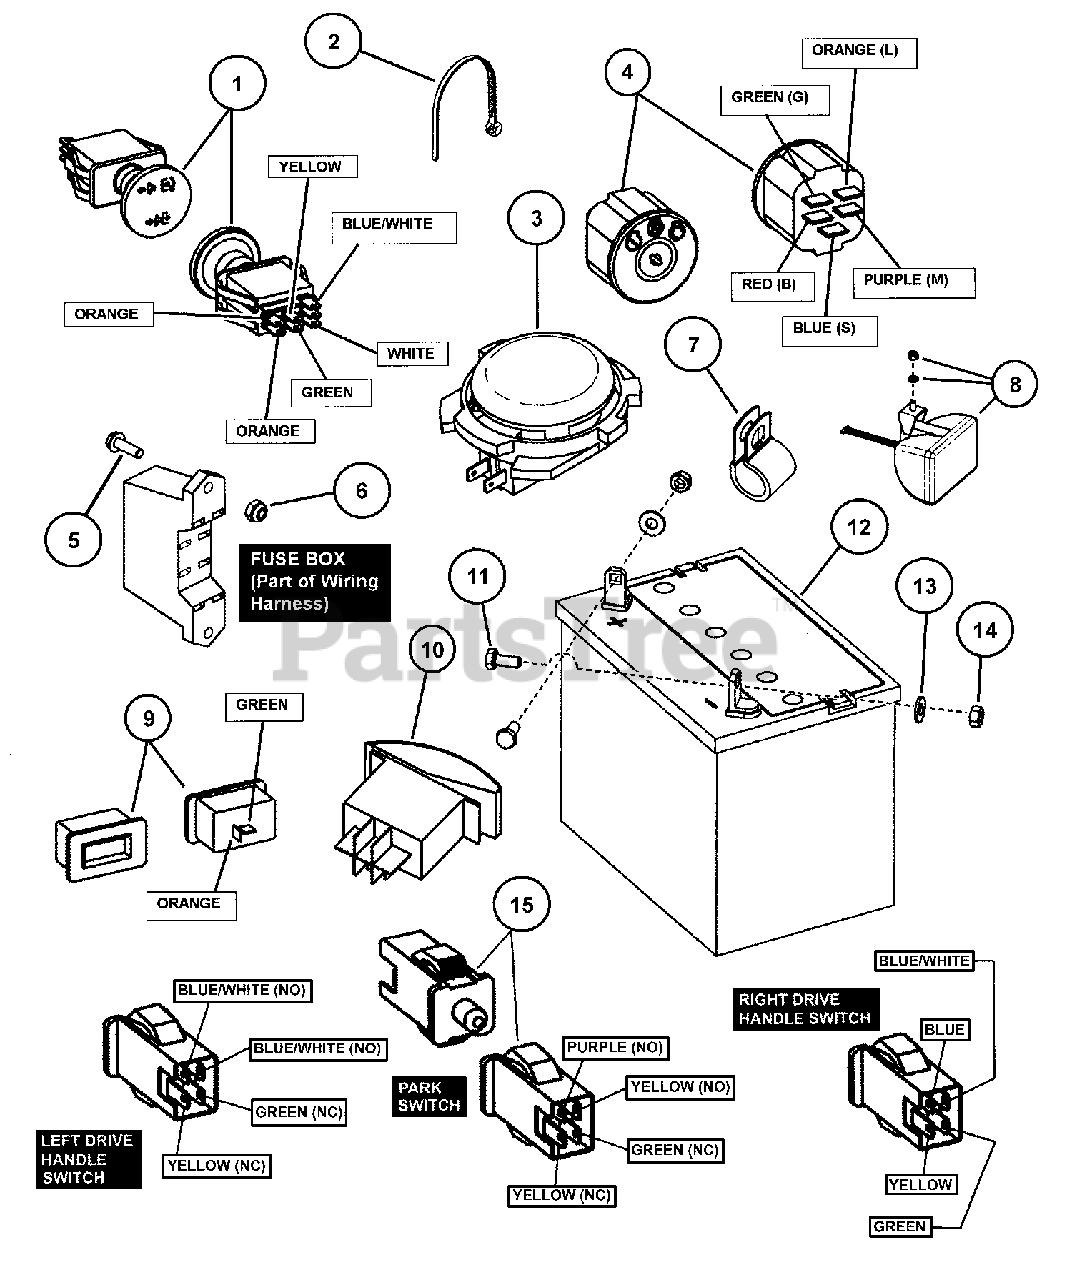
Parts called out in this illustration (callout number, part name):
1	* SWITCH, PTO, Yellow
2	CABLE TIE, 7" Long
3	S WITCH, Seat, NC
4	*SWITCH, Ignition
5	SCREW, #10-32 x 5/8" Hex Washer Self-Tap
6	NUT, #10-32 Nyloc
7	CLIP, Harness
8	HEADLIGHT, w/Connectors
9	* HOUR METER w/Flash Alerts
10	* SWITCH, Lights
11	SCREW, 1/4-20 x 5/8" Hex Head Cap GR 5
12	BATTERY, 11 Plate 375CCA- Wet
13	WASHER, 1/4" Flat
14	NUT, 1/4-20 Hex Center Lock
15	SWITCH, DP NO/NC Snap-In
